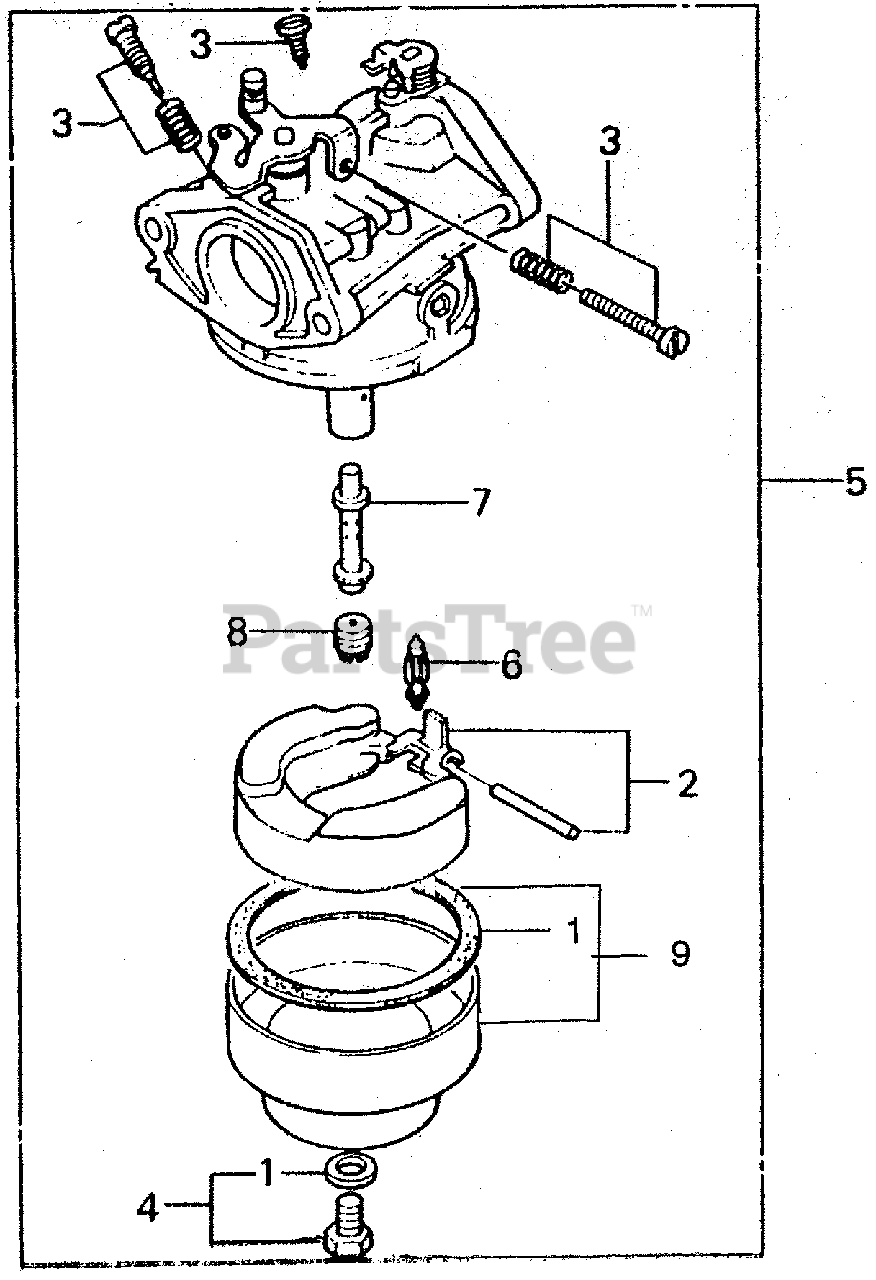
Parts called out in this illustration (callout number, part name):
1	GASKET SET
2	FLOAT SET
3	SCREW SET A
3	SCREW SET A (CARBURETOR NO.) (NOT AVAILABLE)
4	SCREW SET B
5	CARBURETOR ASSY.
6	VALVE, FLOAT
7	NOZZLE, MAIN
8	JET, MAIN (#60) (Honda Code 0635474). (CARBURETOR NO.)
8	JET, MAIN (#62) (Honda Code 0635482). (CARBURETOR NO.)
8	JET, MAIN (#65) Use up to Engine SN BB30A D.
9	CHAMBER SET, FLOAT
